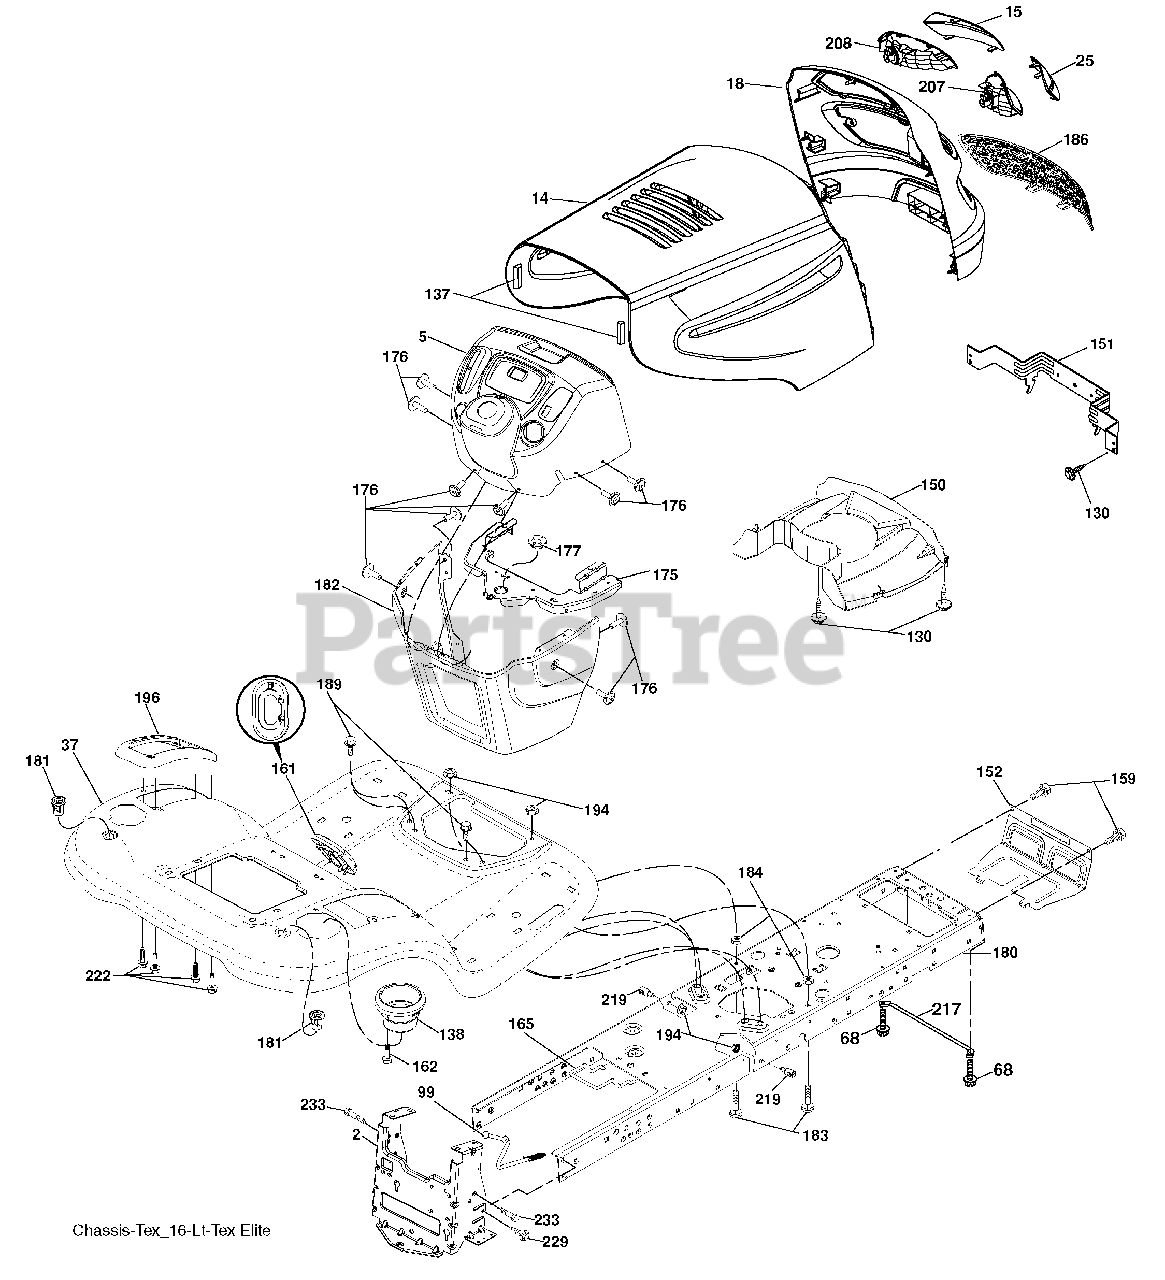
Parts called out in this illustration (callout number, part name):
2	Drawbar
5	Dash
14	Hood
15	Lens Grille LH
18	Grille
25	Lens Grille RH
37	Fender
68	Screw 5/16-18 x 1/2
99	Rod Asm Bypass
130	Screw 10 x 3/4 Single Lead-Hex
137	Bumper Hood
138	Cupholder
150	Duct Heat Hood
151	Bracket Pivot
152	Shield Browning/Debris
159	Screw Hexwsh Thdrol 3/8-16 x 3/4
161	Window Fuel
162	Screw Hex Wsh Hi-Lo 1/4 x 1/2 UNC
165	Bracket Support Tank
175	Crossmember
176	Screw 10-24 x 5/8 Wshd Qdrx
177	Bushing Steering
181	Bushing Mtg. Fender Crgo.
182	Dash Lower
183	Bolt Fin Hex 5/16-18 x 1-1/4
184	Spacer Fender
189	Screw 5/16-18 x 3/4
194	Nut Lock Hex Flange 5/16-18
196	Console Asm. Deck Lift
207	Bezel RH
208	Bezel LH
217	Rod Pivot Chassis/Hood
219	Stud Fastener
222	Screw thd Roll 1/4-20 x 5/8
229	Screw 3/8-16 x 1
233	Bolt Shoulder
